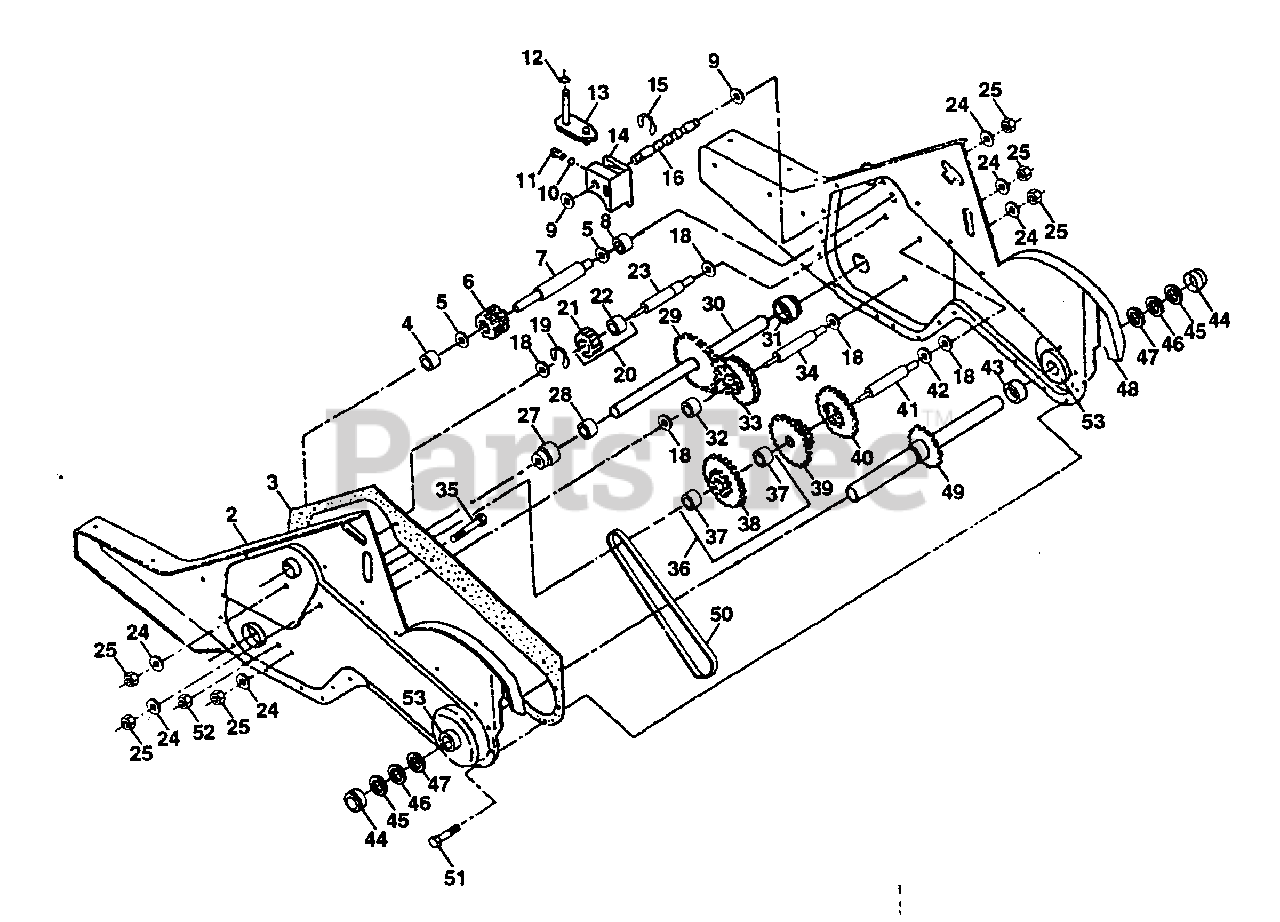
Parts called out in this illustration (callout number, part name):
1	Transmission Assembly (Includes Key Nos. 2-52)
2	Gearcase, L.H. w/Bearing (Includes Key No. 4)
3	Gasket, Gearcase
4	Bearing, Needle
5	Washer, Thrust 5/8 x 1.10 x 1/32
6	Pinion, Input
8	Bearing, Needle
10	Ball, Steel
11	Spring, Shift, Fork
16	Shaft, Shift
20	Gear, Assembly, Reverse Idler (Includes Key Nos. 21 and 22)
21	Gear, Reverse Idler
22	Bearing, Needle
23	Shaft, Reverse Idler
24	Washer, Lock 7/16
25	Nut, Hex 7/16-20
27	Bearing, Shaft, Ground Drive L.H.
28	Spacer 0.765 x 1.125 x 1.23
29	Chain #35-50 Pitch
30	Ground Shaft Assembly
31	Bearing, Shaft, Ground Drive R.H.
32	Spacer 0.70 x 1.00 x 1.150
33	Sprocket and Gear Assembly
34	Shaft, Reduction (2nd)
35	Screw, Whiz, Lock 5/16-18 x 3-1/2
36	Sprocket Assembly w/Bearing (Includes Key Nos. 37 and 38)
37	Bearing, Needle
38	Sprocket, Tine
39	Gear, Cluster, Red 1st & 2nd
40	Gear, Reverse
41	Shaft, Reduction (1st)
42	Washer, Thrust
43	Spacer 1.01 x 1.75 x 0.760
44	Cup, Formed
46	Seal, Ring, Rubber
47	Seal, Oil
48	Gearcase, R.H. w/Bearing (Includes Key No. 8)
49	Shaft, Tine
50	Chain, Roller #50-50 Pitch
51	Screw 1/4-20 x 1/2
52	Nut, Hex 5/16-18
53	Kit, Bearing
